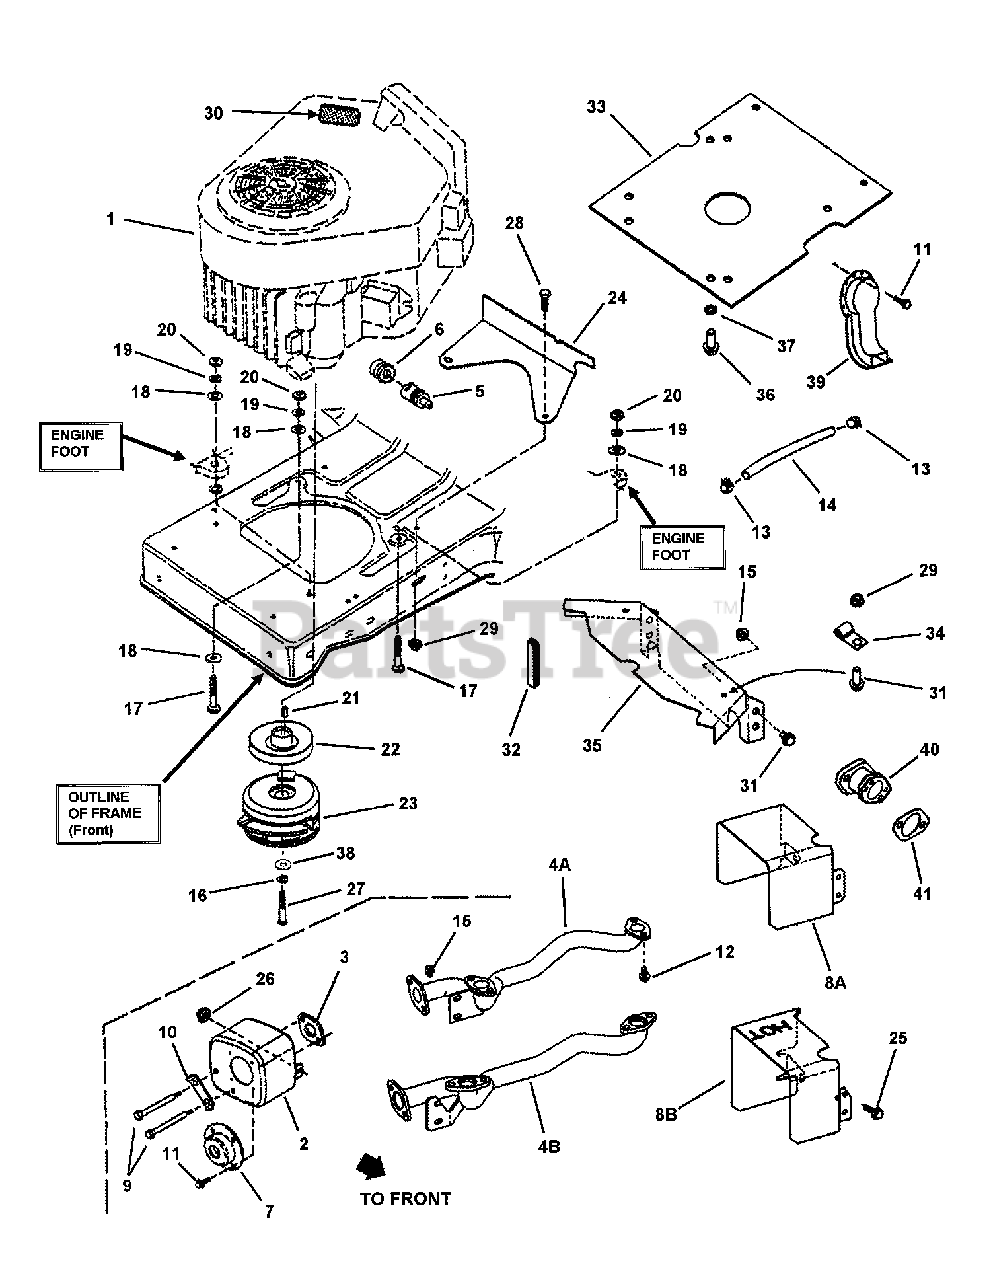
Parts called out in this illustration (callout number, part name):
2	MUFFLER, 16HP B&S (shown)
2	MUFFLER, 14.5HP Briggs Engine
3	GASKET, Muffler/Exhaust (1.18" I.D.; 1.88" hole centers)
3	GASKET, Muffler/Exhaust, 20 HP Intec (1.00" I.D.; 1.968" hole centers)
4A	MANIFOLD, Exhaust
4B	WELDMENT, Manifold 16HP
5	ASSEMBLY, Oil Valve
6	EXTENSION, Oil Drain
7	DEFLECTOR, Exhaust (Direct Out)
8A	SHIELD, Muffler/Heat
8B	SHIELD, Muffler/Heat
9	SHOULDER BOLT, 5/16-18 thread x 4"
10	SCREW LOCK
11	SCREW, #8-18 x 1/2" Hex Head Sheet Metal
12	SCREW, 5/16-18 x 1/2" Hex Washer Self-Tap
13	CLAMP, .490 x .31
14	FUEL LINE, 14" long
14	FUEL LINE, 10" long
14	FUEL LINE, 3-3/4" long
15	NUT, 5/16-18 Hex Flange Lock, GR 5
16	WASHER, 7/16" Split Lock
17	SCREW, 5/16-18 x 1-3/4" Hex Head Cap, GR 5
18	WASHER, 5/16" Flat
19	WASHER, 5/16" Split Lock
20	NUT, 5/16-18 Hex, GR 5 or B
21	KEY, 1/4" Square x 3/4" long
21	KEY, 1/4 Square x 1-3/4"
22	PULLEY, Traction Drive
22	PULLEY, Traction Drive 42&48 TT K46
23	CLUTCH/BRAKE
23	ELECTRIC CLUTCH, Ogura MA-GT-DX11CU
24	SHIELD, Muffler/Heat, B&S 16HP
25	SCREW, 1/4-20 x 5/8" Hex Head Cap, GR 5
26	NUT, 1/4-20 Hex Flange Lock
27	SCREW, 7/16-20 x 2-1/2" (Special), GR 5
28	SCREW, 5/16-18 x 1" Hex Head Cap, GR 2
29	NUT, 5/16-18 Hex Flange Lock, GR 5
30	DECAL, Warning-Speed Setting 14, 16, & 18 HP ENGINES
31	BOLT, 5/16-18 x 5/8" Hex Flange Lock
32	TRIM, Heat Shield (2" long)
32	TRIM-Heat Shield (3" long)
33	PLATE, Engine- Briggs Engine
34	CLIP, "J" Open Type .4 Bundle Dia., .281 Dia. Hole
35	HEAT SHIELD, B&S V-Twin Engine
36	SCREW, 3/8-16 x 1" Hex Washer Self-Tap
37	WASHER, 5/16" Split Lock
38	WASHER, 7/16 I.D. x 1-1/2" O.D. x .188 thick
39	WELDMENT, Muffler Deflector
40	ADAPTER, Muffler
41	GASKET, Exhaust (1.25" I.D.; 1.875" hole centers)
